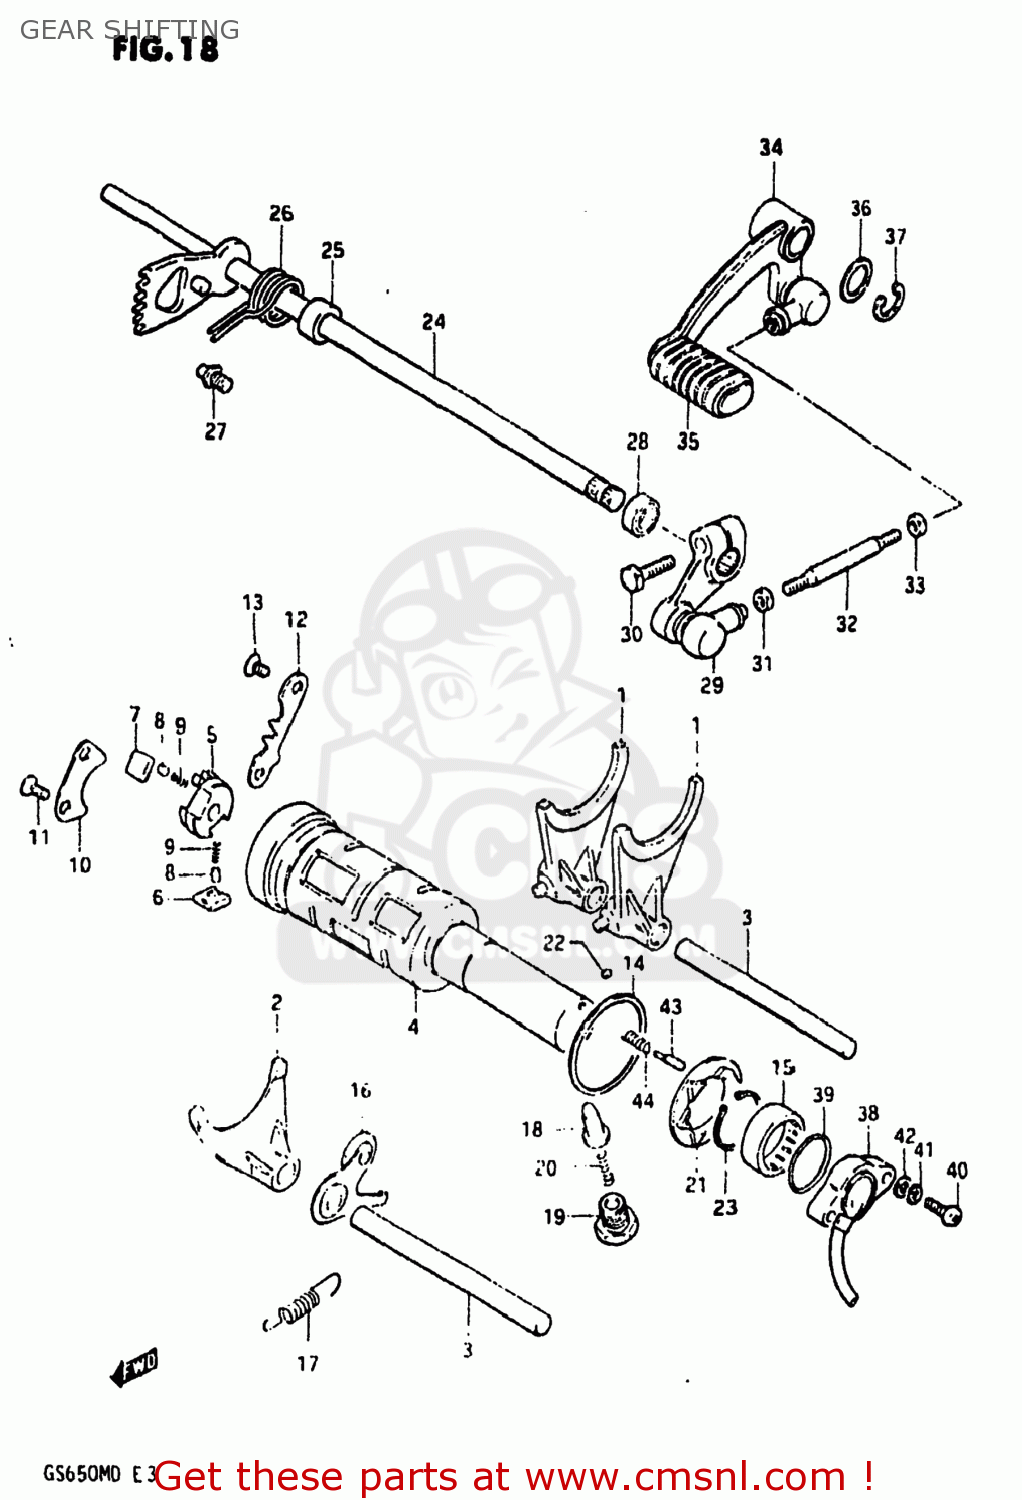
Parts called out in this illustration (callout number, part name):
1	FORK,GEAR SHIFT NO.1
2	FORK,GEAR SHIFT NO.3
3	SHAFT,GEAR SHIFT FORK
4	CAM,GEAR SHIFT
5	RETAINER,GEAR SHIFT CAM
6	PAWL,GEAR SHIFT NO.1
7	PAWL,GEAR SHIFT NO.2
8	PIN(5X8)
9	SPRING
10	LIFTER,GEAR SHIFT PAWL
11	SCREW
12	GUIDE,GEAR SHIFT
13	SCREW
14	WASHER(40X45X1)
15	BEARING(25X32X12)
16	STOPPER,GEAR SHIFTING
17	SPRING
18	STOPPER,GEAR SHIFT CAM NO.2
19	HOLDER,GEAR SHIFT CAM STOP SPR
20	SPRING
21	PLATE,GEAR SHIFT CAM STOPPER
22	PIN 4X6
23	CIRCLIP,25MM
24	SHAFT,GEAR SHIFT
25	SPACER(12X20X15.3)
26	SPRING
27	STOPPER,GEAR SHIFT CAM
28	OIL SEAL
29	ARM,GEAR SHIFT LINK
30	BOLT
31	NUT
32	ROD,GEAR SHIFT LINK
33	NUT
34	LEVER ASSEMBLY,GEAR SHIFTING
35	RUBBER,PEDAL
36	WASHER(12.5X20X1)
37	CIRCLIP
38	TERMINAL BASE ASSY,GEAR SHIFT
39	O-RING (D:2.4 ID:26.2)
40	SCREW 5X20
41	LOCK WASHER
42	WASHER
43	PIN(5X15.5)
44	SPRING
